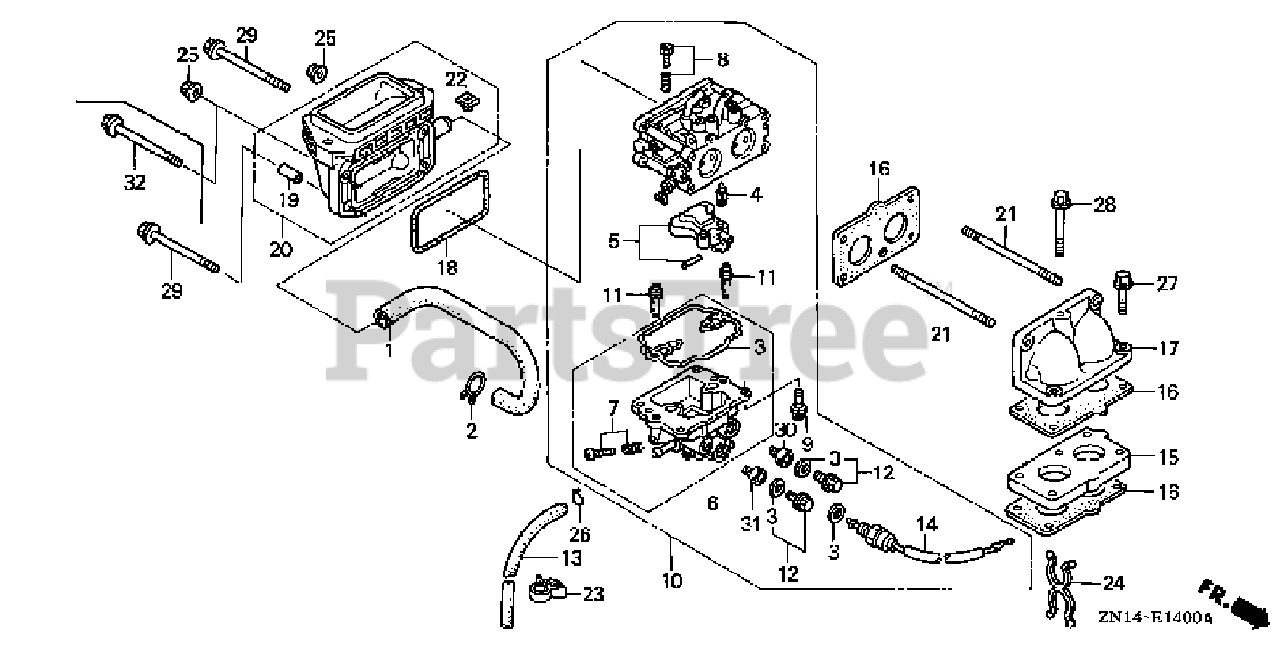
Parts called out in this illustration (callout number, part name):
1	TUBE, BREATHER
2	CLIP, BREATHER TUBE
3	GASKET SET
4	VALVE, FLOAT
5	FLOAT SET
6	CHAMBER SET, FLOAT
7	SCREW SET, DRAIN
8	SCREW SET
9	SCREW-WASHER
10	CARBURETOR ASSY. (TB01A A)
11	JET, SLOW (#54)
12	PLUG SET
13	TUBE, DRAIN
14	VALVE ASSY., SOLENOID
15	INSULATOR, CARBURETOR
16	GASKET, CARBURETOR
17	ELBOW, MANIFOLD
18	GASKET, AIR CLEANR
19	COLLAR A, AIR CLEANER
20	ELBOW, AIR CLEANER
21	BOLT, STUD (6X85)
22	NUT, INSERT (6MM)
23	CLIP B, CABLE
24	CLIP, PURSE LOCK
25	NUT, FLANGE (6MM)
26	CLIP, TUBE (B8)
27	BOLT, FLANGE (6X30)
28	BOLT, FLANGE (6X65)
29	BOLT, FLANGE (6X90)
30	JET, MAIN (#92)
30	JET, MAIN (#96)
30	JET, MAIN (#102)
31	JET, MAIN (#94)
31	JET, MAIN (#98)
31	JET, MAIN (#100)
32	BOLT, FLANGE (6X90)
